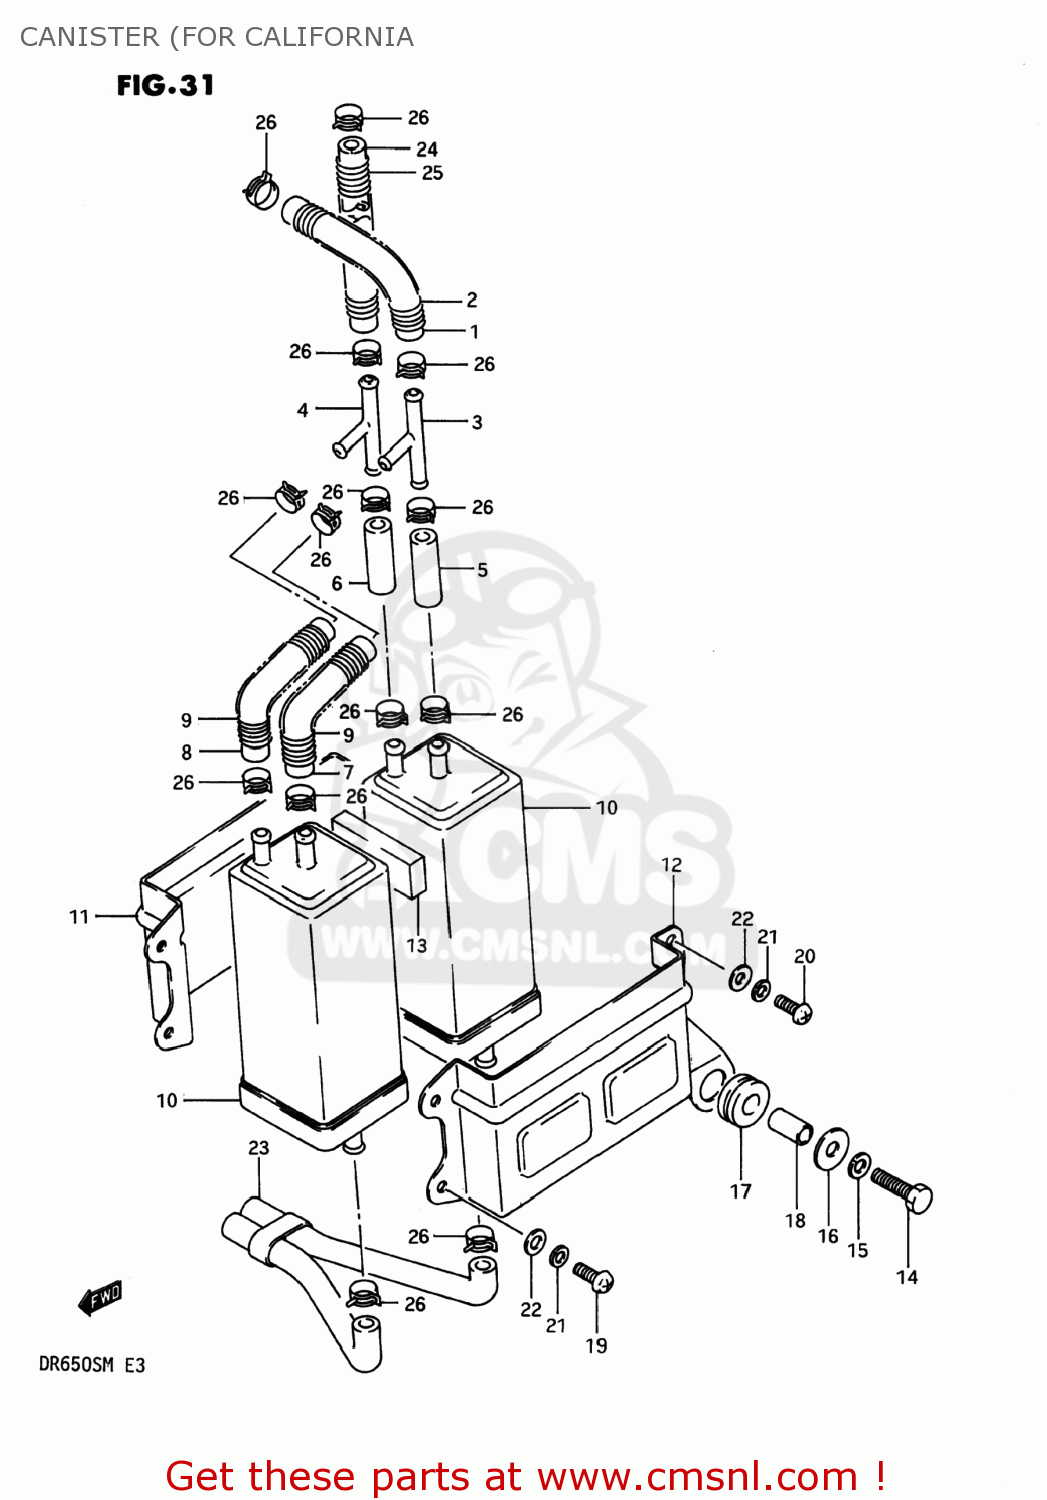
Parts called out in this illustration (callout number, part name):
1	HOSE
2	(CA) SPRING
3	(CA) CLIP
4	VALVE,FUEL TANK BREATHER
5	PLATE,FUEL TANK BREATHER NO.2
6	SCREW
7	PIPE
8	PIPE CANISTER
9	HOSE
10	HOSE
11	(CA) SPRING
12	(CA) CLIP
13	HOSE
14	HOSE
15	(CA) CLIP
16	HOSE (5.4X11.4X600)
17	(CA) SPRING
18	(CA) CLIP
19	CANISTER ASSY,CHARCOAL
20	(CA) PLATE,CANISTER,OUTER
21	PLATE,CANISTER FITTING
22	SCREW
23	SCREW
24	CUSHION,CANISTER
25	BOLT
26	WASHER,LOCK
27	WASHER(6.5X18X1)
28	SPACER(6.4X9X16)
29	CUSHION
30	HOSE,CANISTER DRAIN NO
31	HOSE,CANISTER DRAIN NO
32	PIPE COMP,CANISTER DRAIN HOSE
33	HOSE(7X11X600)
34	(CA) CLIP
35	CLAMP
